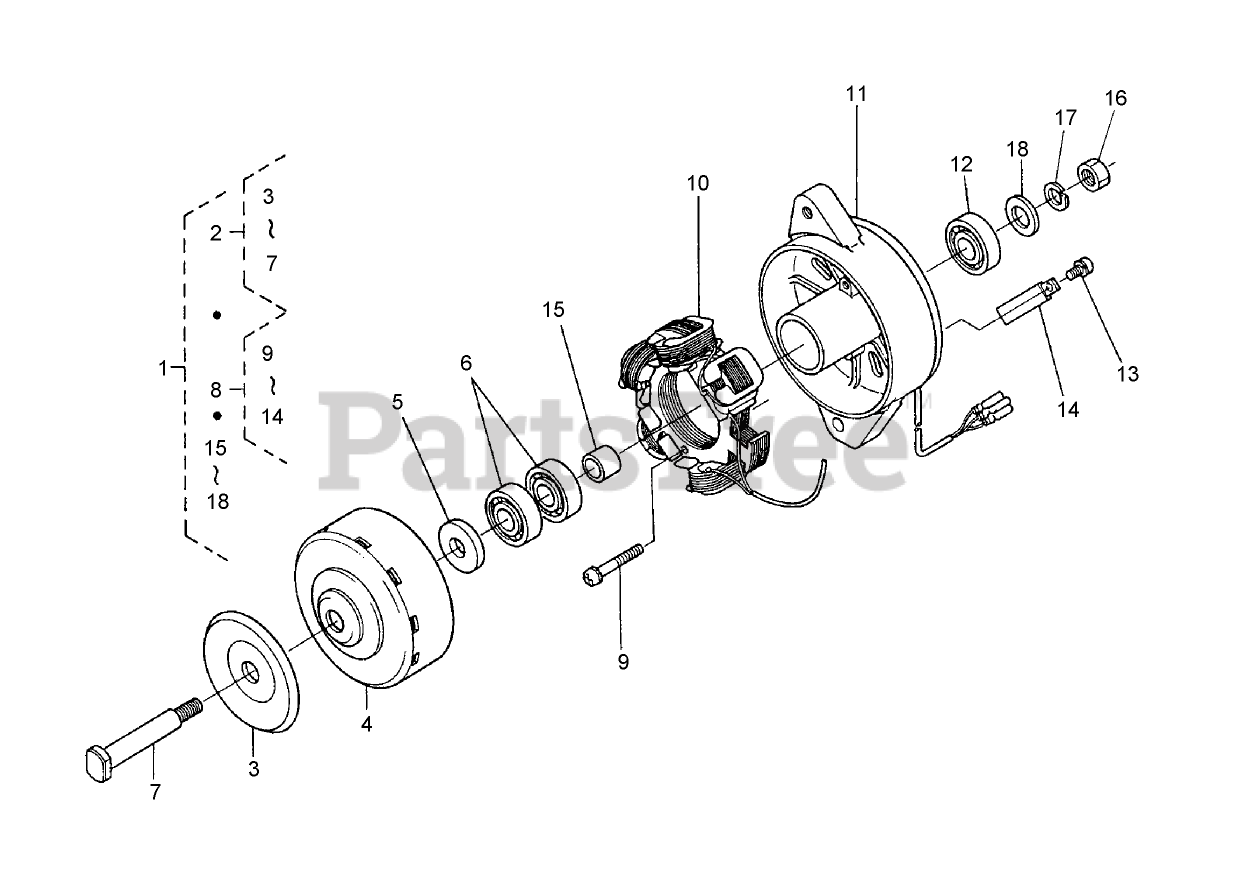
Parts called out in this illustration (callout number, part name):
1	DYNAMO ASM
2	ROTOR ASM
3	PULLEY
5	COLLAR
6	BEARING-BALL
7	SHAFT-FAN
8	STATOR ASM
9	SCREW-HEAD, ROUND
10	STATOR
12	BEARING-BALL
13	SCREW-HEAD, ROUND
14	CLAMP-CORD
15	COLLAR
17	WASHER-SPRING
18	WASHER-PLAIN
